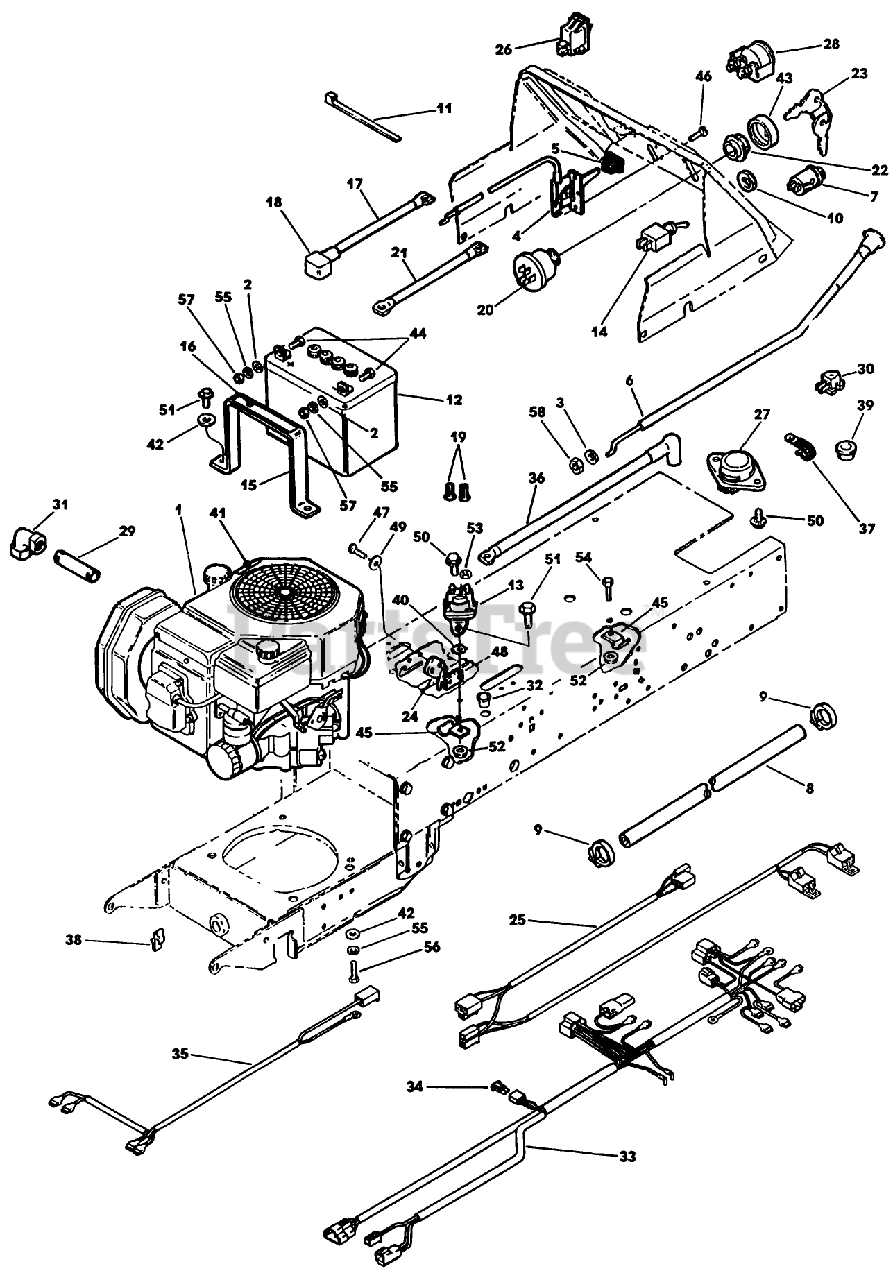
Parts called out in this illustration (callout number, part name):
3	WASHER
5	THROTTLE KNOB
6	CONTROL,CHOKE
7	LIGHT-PTO INDICTOR
13	SOLENOID
14	SWITCH-PTO W/SAFTY
22	NUT
23	KEY
24	SWITCH
26	SWITCH ASSEMBLY
27	SWITCH,SEAT
30	SWITCH
38	CLIP
43	BEZEL
44	SCREW - HEX
53	NUT-HEX
54	SCREW-HH
57	NUT SS
58	NUT-HEX
